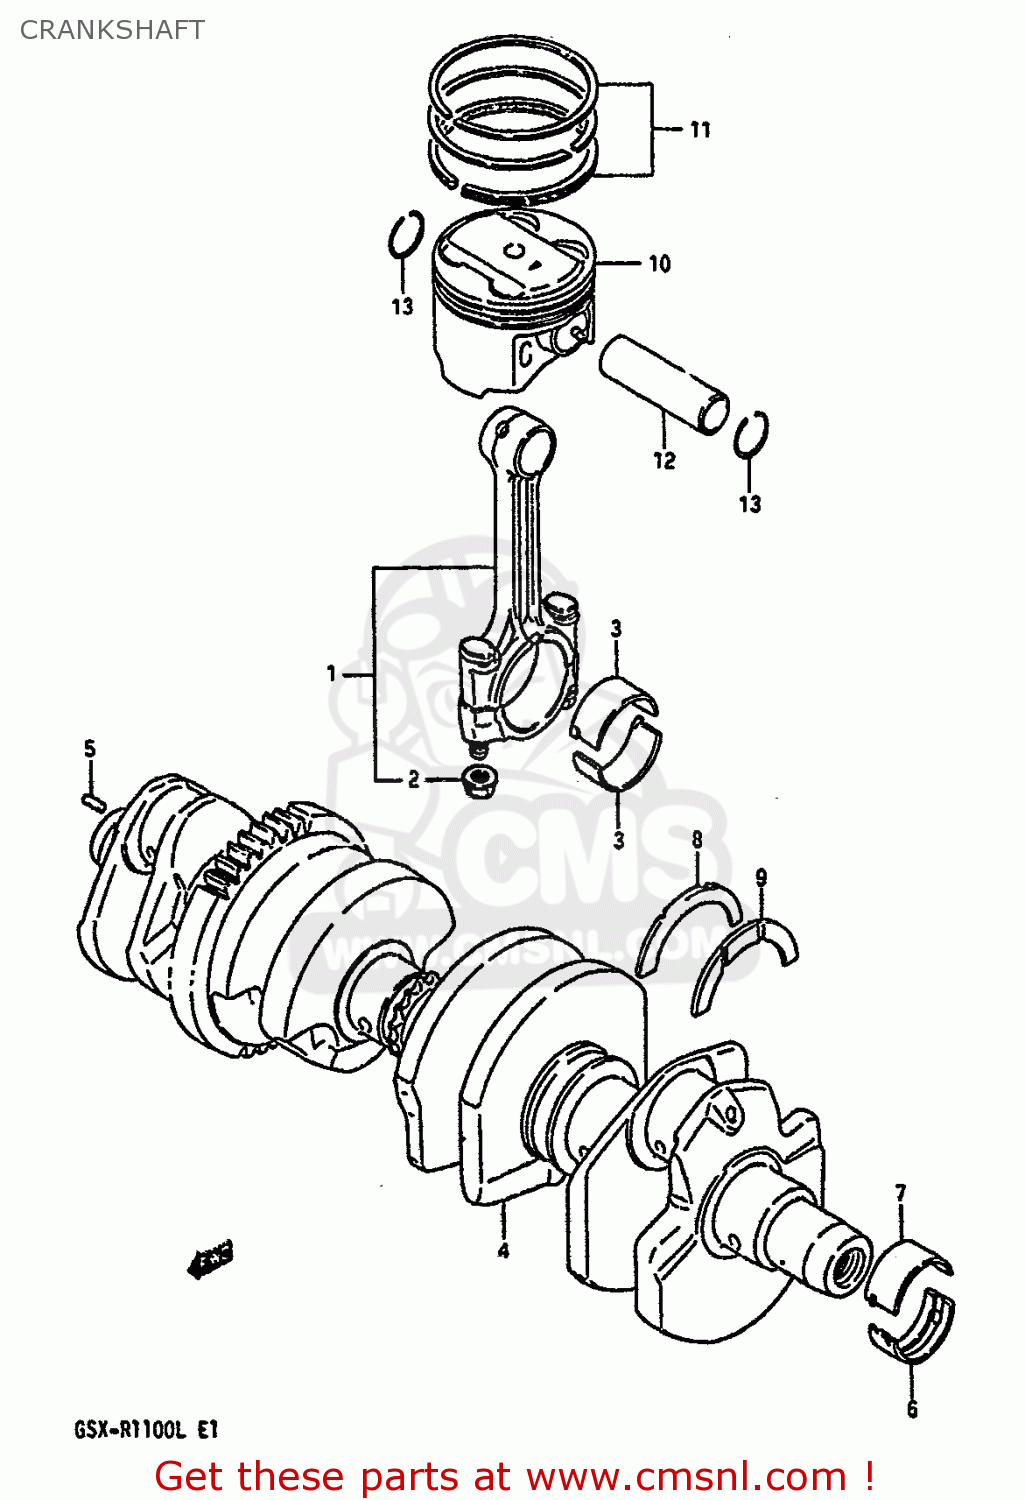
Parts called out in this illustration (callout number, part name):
1	CONNECTING ROD ASSEMBLY
2	NUT
3	BEARING,CRANK PIN
4	CRANKSHAFT
5	PIN
6	BEARING,CRANKSHAFT LWR
7	BEARING,CRANKSHAFT UPR
8	BEARING,CRANK THRUST(GREEN)
9	BEARING,CRANK THRUST(RED)
10	PISTON
11	RING SET,PISTON
12	PIN,PISTON
13	CIRCLIP,PISTON PIN
